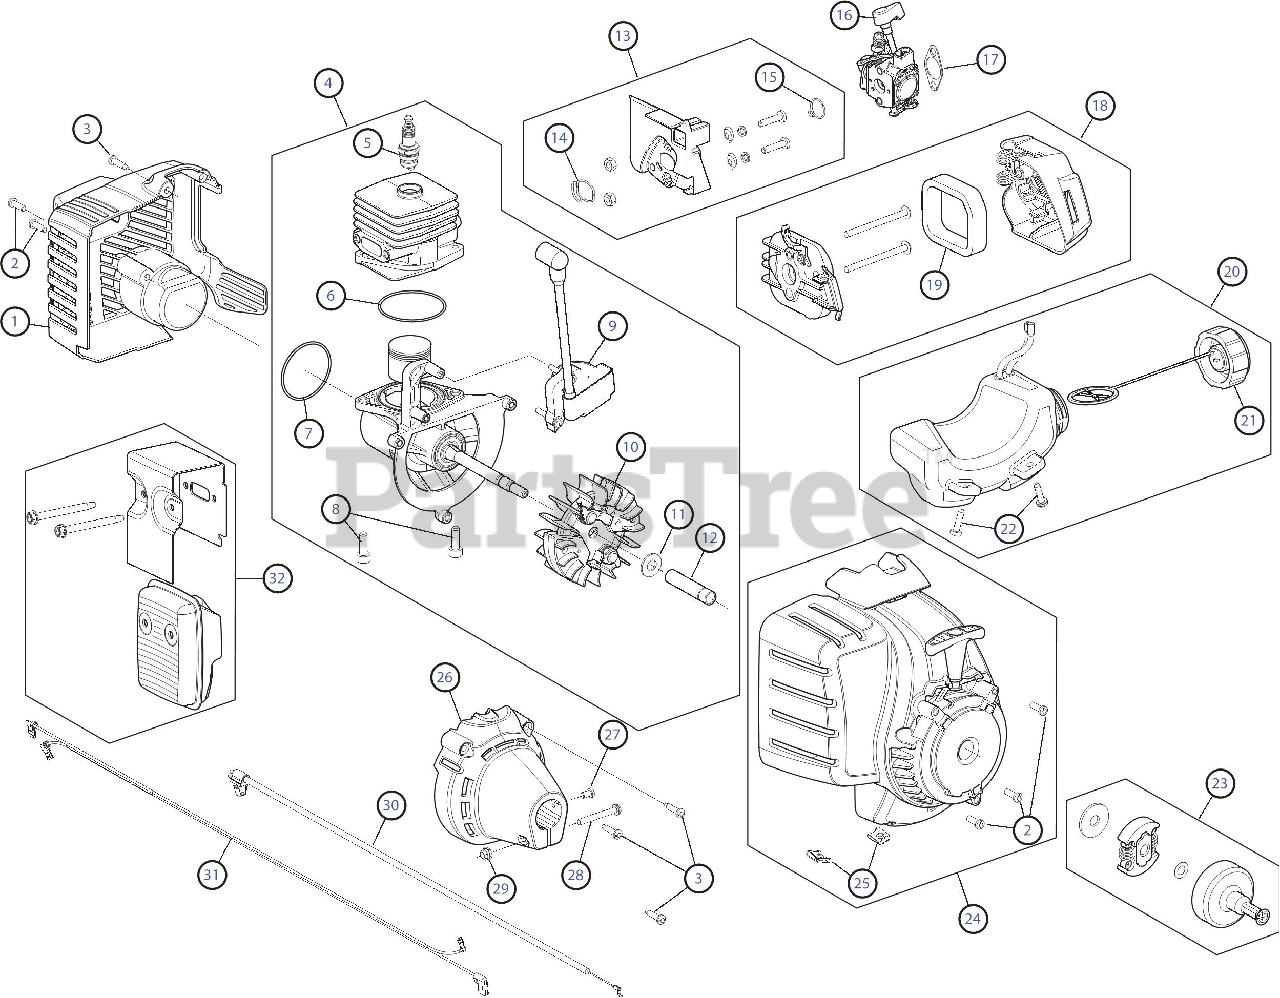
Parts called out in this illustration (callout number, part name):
1	Rear Cover Assembly (Incl. 2 & 3)
2	Housing Screw
3	Cover Screw
4	Short Block Assembly (Incl. 5 - 12)
5	Spark Plug
6	Crankcase O-Ring
7	O-Ring
8	Crankcase Bolt
9	Module Assembly
10	Flywheel Assembly
11	Washer
12	Spacer
13	Insulator Assembly (Incl. 14 & 15)
14	Insulator O-Ring
15	Carburetor O-Ring
16	Carburetor
17	Air Cleaner Gasket
18	Air Cleaner Cover Assembly (Incl. 19)
19	Air Cleaner Filter
20	Fuel Tank Assembly (Incl. 21 & 22)
21	Fuel Tank Cap
22	Fuel Tank Screw
23	Clutch Assembly
24	Starter Housing (Incl. 2 & 25)
25	U-shaped Nut
26	Clutch Cover (Incl. 3)
27	Anti-rotation Screw
28	Clamp Screw
29	Clamp Nut
30	Throttle Cable
31	Lead Wires
32	Muffler Assembly
